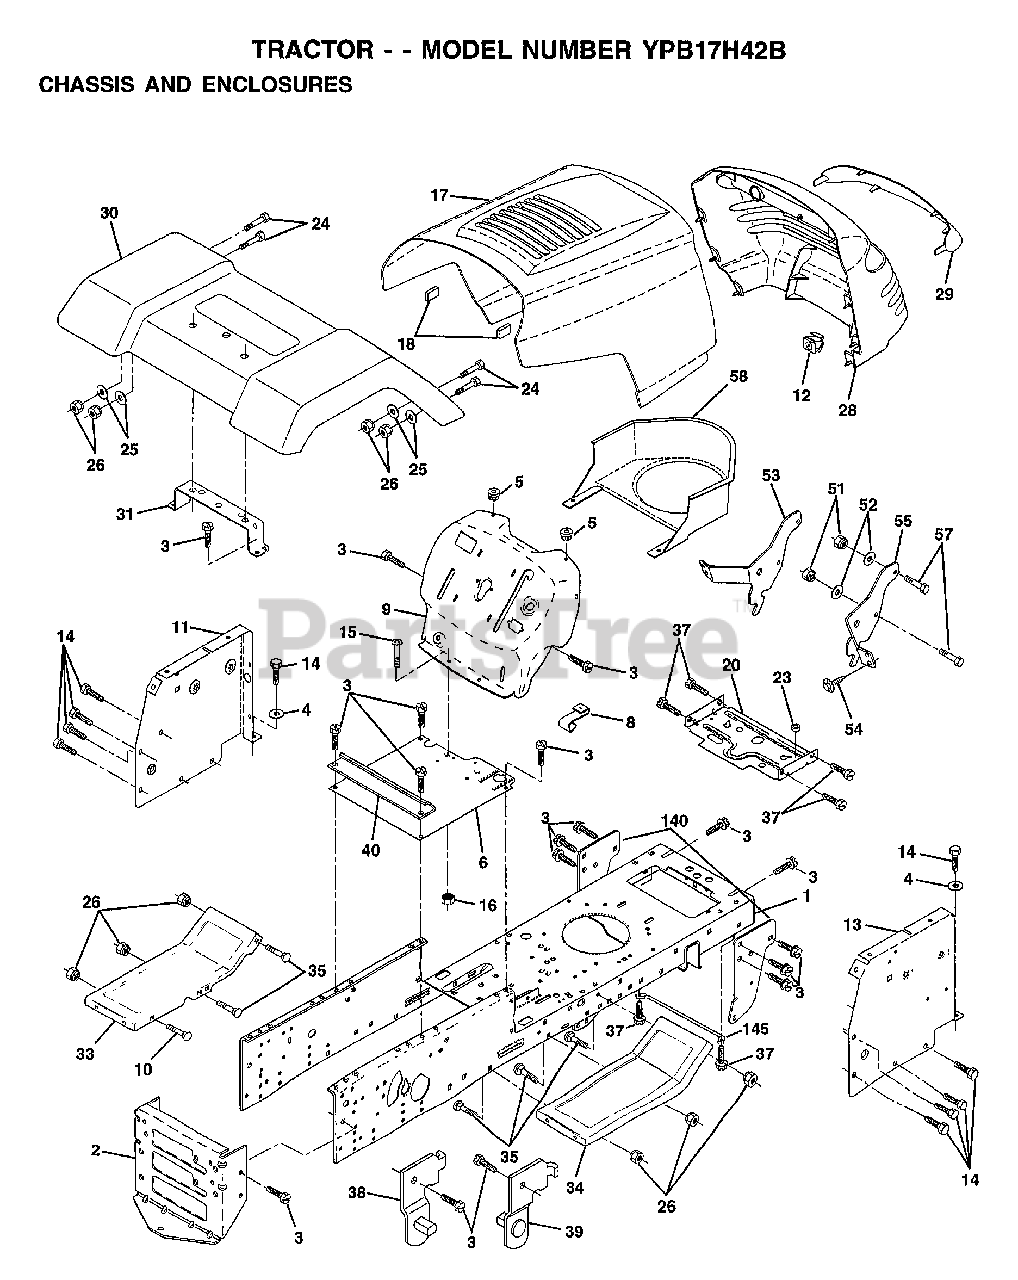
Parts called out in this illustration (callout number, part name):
1	CHASSIS.STAMPING
3	SCREW
4	WASHER
5	BUMPER-HOOD/DASH
6	SADDLE
8	CLIP.RETAINER
9	DASH.SILKSCREEN
11	"PANEL-DASH,LH"
12	CLIP.TINNERMAN
13	PANEL.ASM.DASH.RH
14	SCREW LT
15	SCREW
17	"HOOD W/TRIM,MS428"
20	"PLATE-MTG,BATT/FU"
24	BOLT
25	WASHER
26	NUT
28	GRILL
29	GRILLE.LENS
30	FENDER.LTST.WLDMNT.W/SHIFT
31	BRACKET SUPT FEND
33	FOOTREST PNT LH
34	FOOTREST.RH.LT/GT
35	BOLT
37	SCREW LT
38	BRACKET ASM LH
39	BRACKET ASM RH
40	SPACER FENDER LT
51	NUT
52	WASHER
53	BRACKET.GRILLE.LH
54	SCREW.HEX.WS.HD
55	BRACKET.GRILLE.RH
58	AIR DUCT
140	BRKT SUSPENSION
145	"ROD POVOT,CHASSIS"
